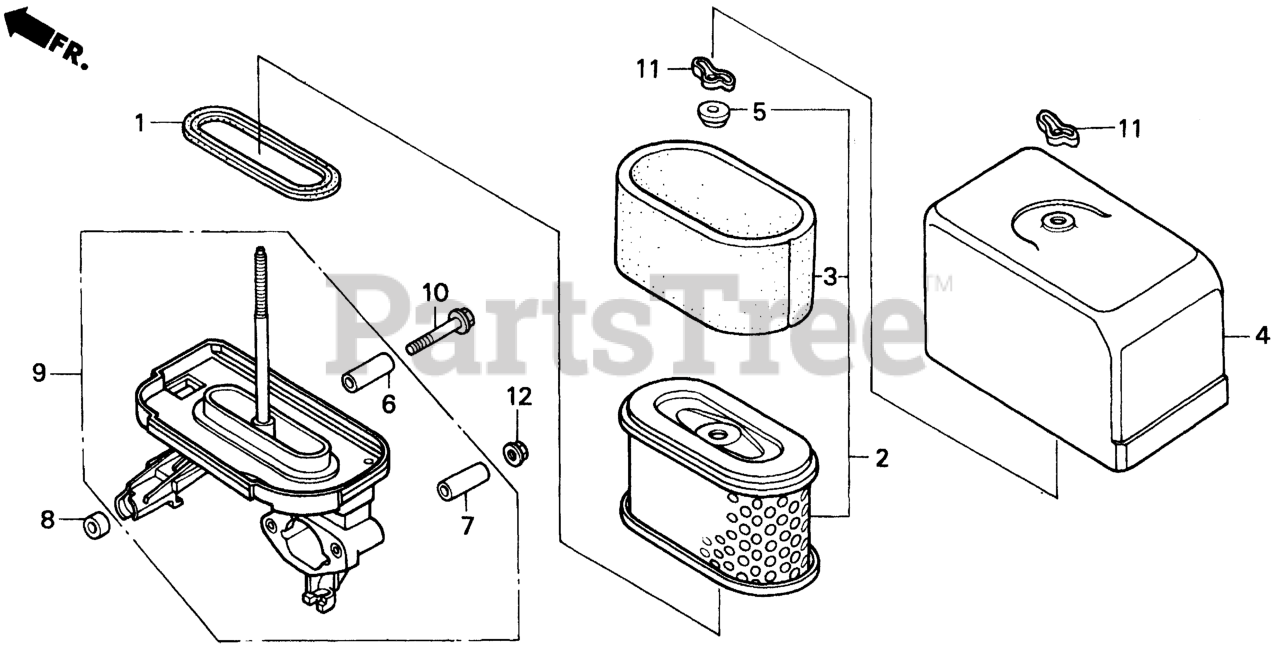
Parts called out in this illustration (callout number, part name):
1	GASKET, ELBOW
2	ELEMENT, AIR CLEANER (METAL BASE)
3	FILTER,OUTER
3	FILTER (OUTER)
4	COVER, AIR CLEANER (DUAL)
5	GROMMET, AIR CLEANER
6	COLLAR, AIR CLEANER Use up to Engine SN 1786084.
7	COLLAR, AIR CLEANER
8	SPACER, AIR CLEANER ELBOW
9	ELBOW, AIR CLEANER
10	BOLT, FLANGE (6X45)
11	WINGNUT, TOOL BOX SETTING
12	NUT, FLANGE (6MM)
